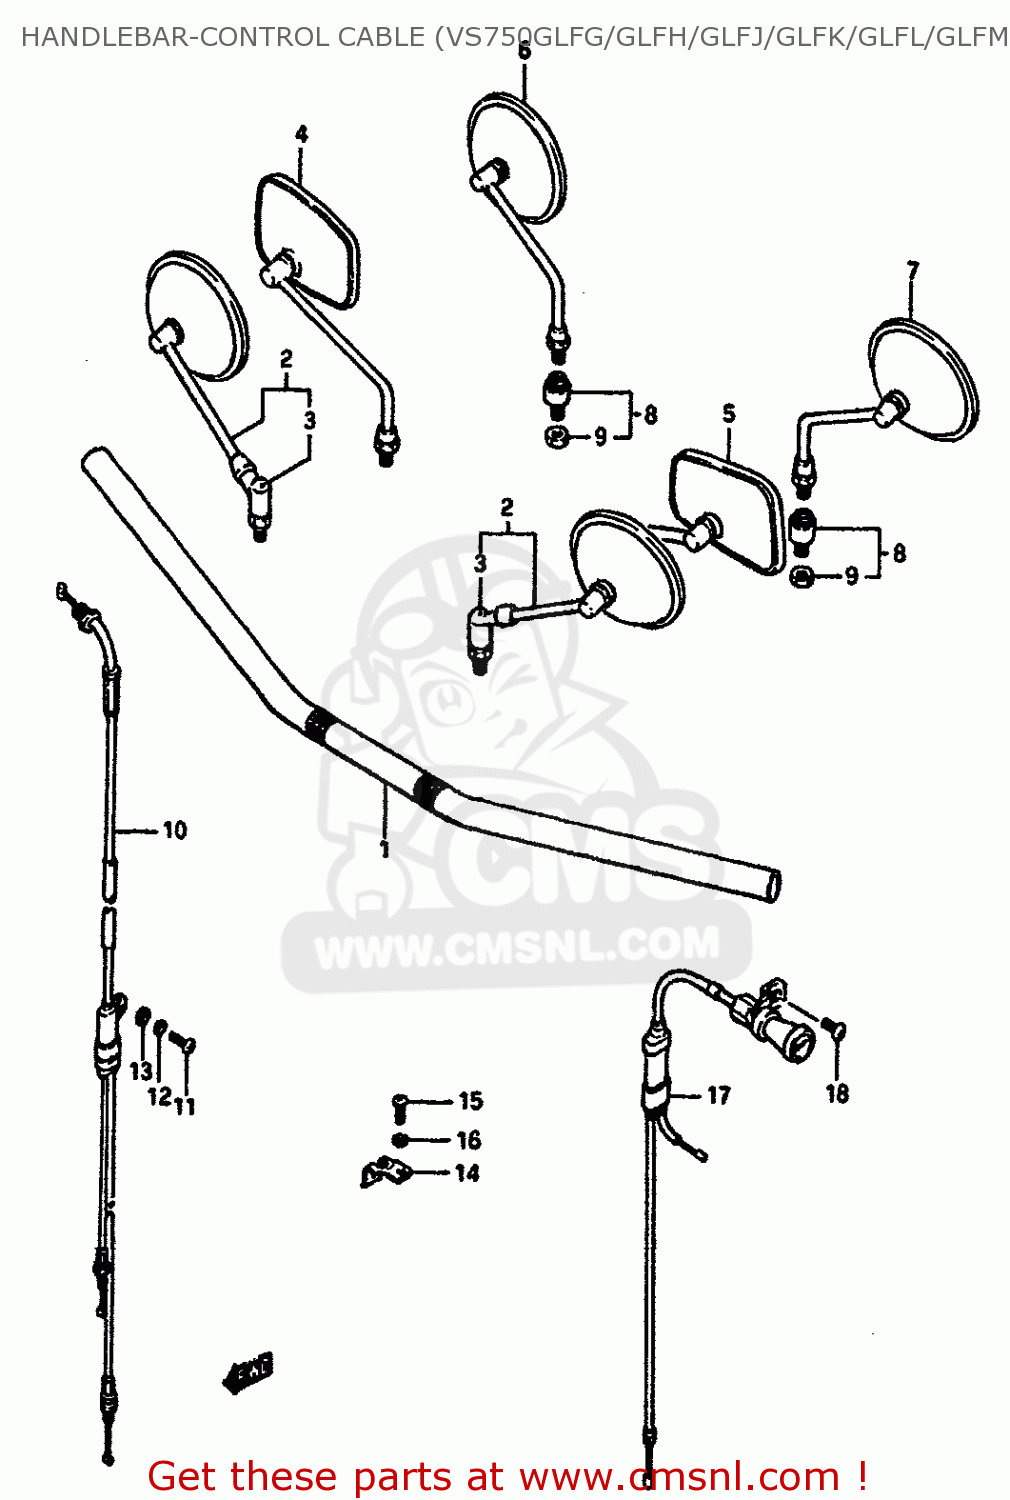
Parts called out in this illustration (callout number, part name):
1	HANDLEBAR
2	MIRROR ASSY,R.
3	CAP
4	MIRROR ASSY,RR VIEW,R
5	MIRROR ASSY,RR VIEW,L
6	MIRROR ASSY RH
7	MIRROR ASSY
8	CUSHION,REAR VIEW MIRROR
9	NUT
10	CABLE ASSEMBLY,THROTTLE
11	SCREW
12	LOCK WASHER
13	WASHER
14	CLAMP,THROTTLE CABLE
15	SCREW
16	LOCK WASHER
17	CABLE ASSEMBLY,STARTER
18	SCREW
